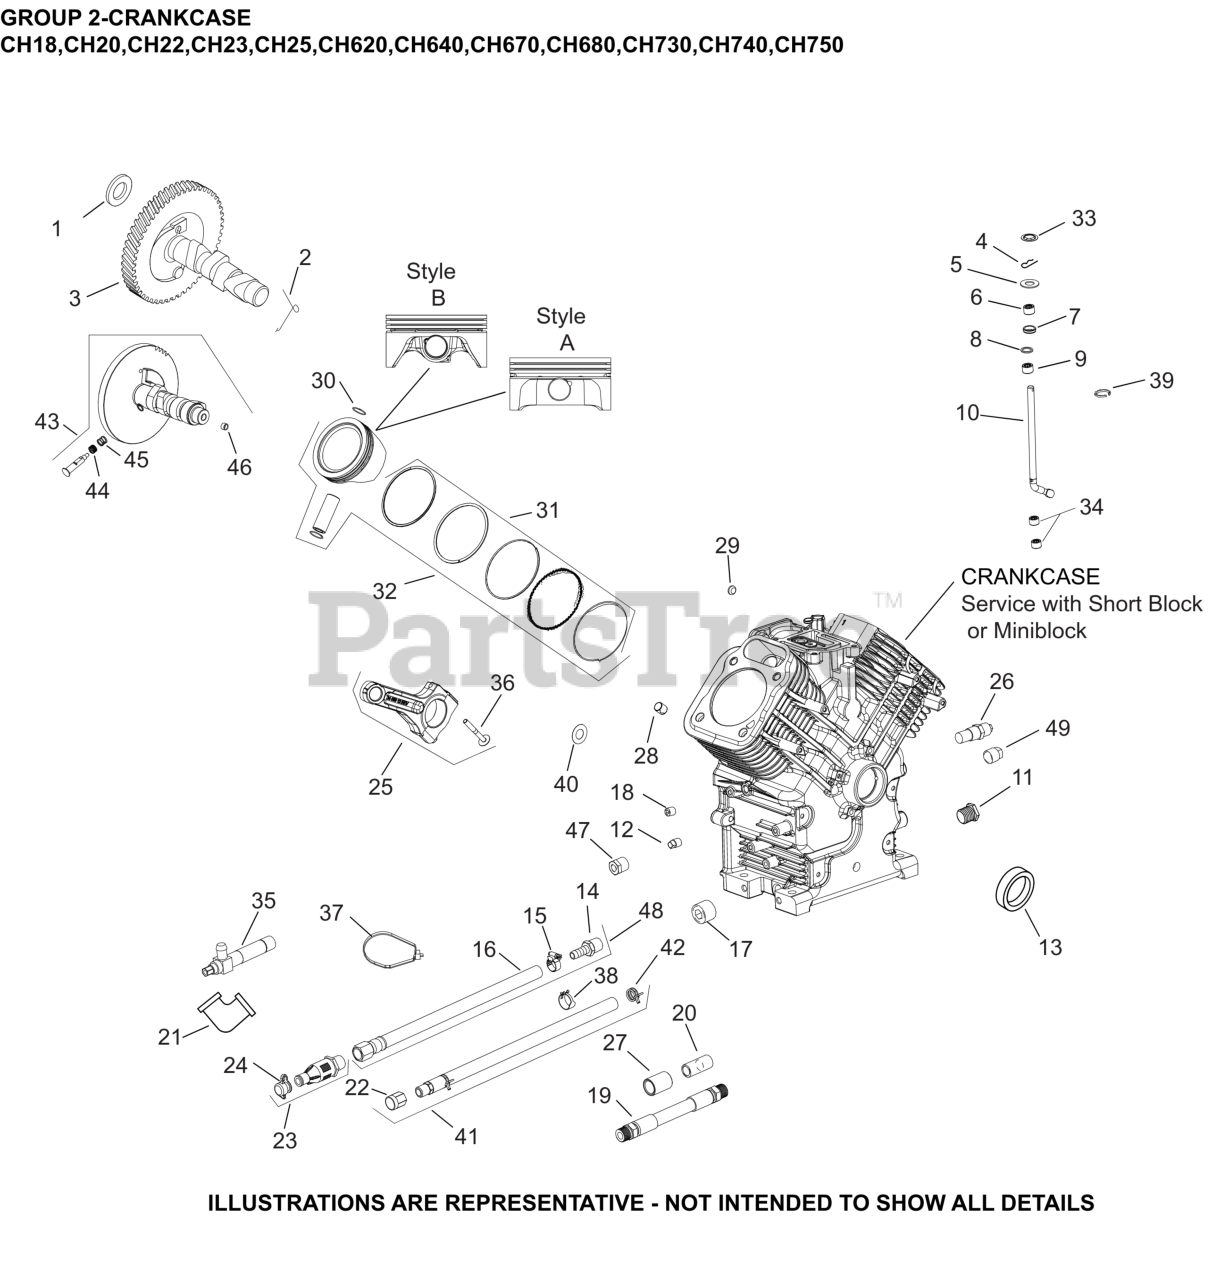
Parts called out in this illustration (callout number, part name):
3	KIT, CAMSHAFT
5	WASHER, FLAT 9 MM
7	SEAL, GOVERNOR CROSS SHAFT
8	WASHER, FLAT 11/32"
10	SHAFT, GOVERNOR CROSS
11	PLUG, HD PIPE 3/8"
13	SEAL, OIL (HELIX LIP)
25	ROD, ASSEMBLY CONNECTING
28	PIN, LOCATING
29	PLUG, CUP
30	RETAINER, PISTON PIN
31	RING SET (STD) STYLE B
31	RING SET (.08) STYLE B
31	RING SET (.25) STYLE B
31	RING SET (.50) STYLE B
32	KIT, PISTON (STD) STYLE B
32	KIT, PISTON (.08) STYLE B-(#DSC)
32	KIT, PISTON (.25) STYLE B
32	KIT, PISTON (.50) STYLE B
33	RETAINER, RING
36	KIT, ROD BOLTS-(#25086677S)
